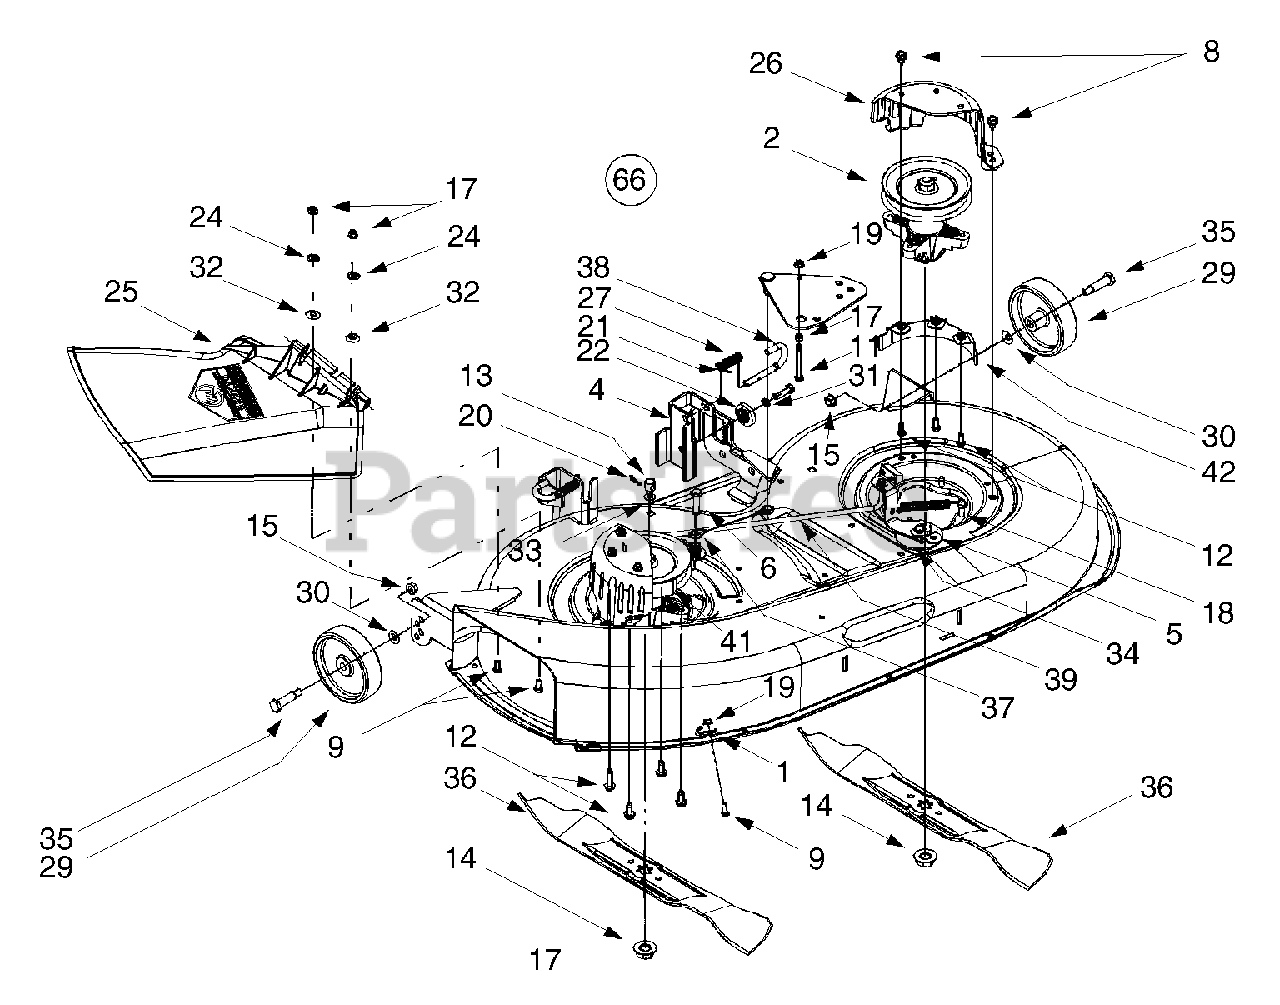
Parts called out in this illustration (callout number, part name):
1	Retainer Hook
2	Spindle Assembly, 5.75 Dia.
5	Deck Brake Assembly, 42-inch Decks
6	Hex Cap Screw, 3/8-16 x 1.5
8	Self-tapping Screw, 5/16-18 x .625
9	Hex Cap Screw, 1/4-20 x .62
11	Hex Cap Screw, 1/4-20 x 2.5
12	Self-tapping Screw, 5/16-18 x .75
13	Ferrule, 5/16-18
14	Hex Flange Nut, 5/8-18
15	Flange Lock Nut, 3/8-16
17	Hex Nut, 1/4-20
18	Hex Lock Nut, 5/16-18
19	Hex Flange Lock Nut, 1/4-20
20	Internal Cotter Pin, .072 x 1.12
21	Cotter Pin, 3/32 x 1.0
22	Deck Adjustment Gear
24	Push Nut. .25 x .5
25	Side Discharge Chute Assembly
26	Belt Cover
27	Compression Spring, .406 x .531 x 1.75
29	Deck Wheel, 5 x 1.38
30	Bell Washer, .401 x .87 x .063
31	Lock Washer, 5/16
32	Bell Washer, .265 x .75 x .062
33	Flat Washer, .344 x .688 x .065
34	Flat Washer, .320 x 3.0 x .125
35	Shoulder Screw, .498 x 1.53
36	Three-in-one Blade, Star Center, 21.23"
37	Bracket Cable, 5.35"
38	Deck Release Pin
39	Deck Brake Rod
